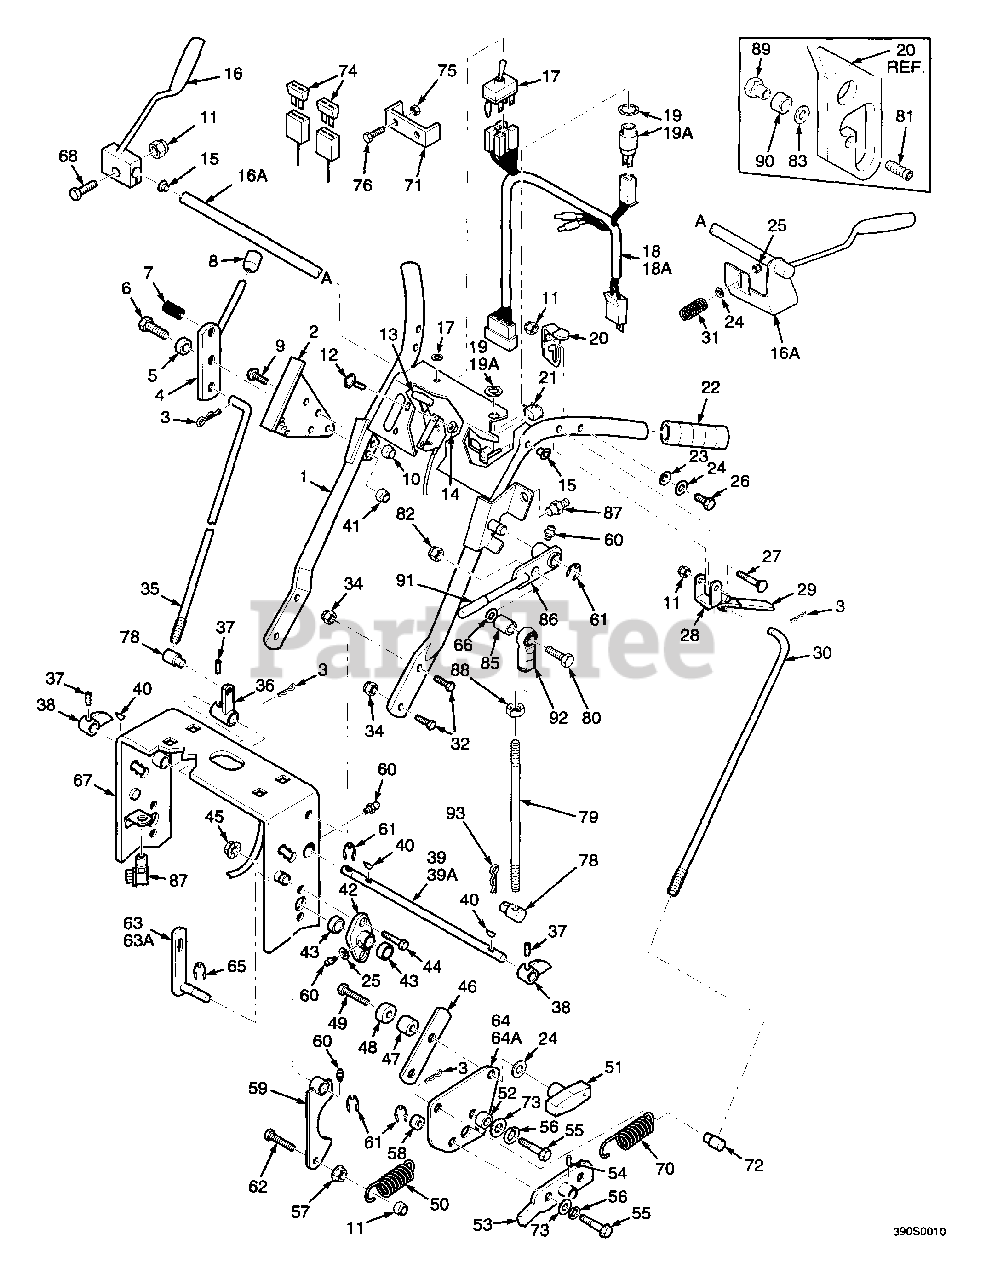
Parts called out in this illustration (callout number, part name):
1	Upper Handle Wlmt. W/Decals
2	Quadrant, Speed Control
3	Hairpin, .094 x 1.19
4	Lever, Speed Adjustment
5	Bushing, Speed Adjustment Lever
6	Hex Head Bolt, 3/8-16 x 1-1/2"
7	Ball Plunger
8	Knob, Speed Adjustment
9	Capscrew, 1/4-20 x 3/4" FHHS
10	Nut, 1/4-20 Elastic Stop
11	Nut, 5/16-18 Elastic Stop
12	Screw, #10-32 x 1/2" PW HD
13	Throttle Control
14	Nut, #10-32 Serr. Flange
15	Bushing
16	Handle, Operator Presence-RH
16A	Handle, Operator Presence-LH (20")
17	Switch, Elec. Clutch Eng.
18	Wire Harness, Manual Start
18A	Wire Harness, Electric Start
19	Key Switch, Manual Srt.
19A	Key Switch, Elec. Start
20	Neutral Latch-RH
20A	Neutral Latch-LH
21	Switch, Neutral Interlock
22	Grip
23	Washer, Curved Spring
24	Flat Washer
25	Lock Washer, 1/4" Int. Tooth
26	Hex Head Bolt, 5/16-18 x 2"
27	Hex Hd. Bolt, 5/16-18 x 2-1/2"
28	Lever, Steering Control
29	Grip, Steering Control
30	Rod, Steering Control
31	Spring, Handle Return
32	Capscr., 3/8-16 x 1" Ser. Flange
33	Lock Washer, 1/4"
34	Nut, 3/8-16 Serr. Flange
35	Rod Steering Control
36	Bellcrank, Speed Control
37	Setscrew, 1/4-28 x 1/4"
38	Cam, Speed Control
39	Jackshaft, Speed Control
40	Key, 1/8 x 1/2" Woodruff
41	Nut, 3/8-16 Elastic Stop
42	Pivot, Pump Ctrl
43	Bushing, 1/2" ID
44	Capscrew, 5/16-18 x 1" Serr. Flg.
45	Nut, 5/16-18 Serrated Flange
46	Bar, Speed Control
46	Bearing, Speed Ctrl. Bellcrank
47	Spacer, Speed Ctrl. Bearing
49	Hex Head Bolt, 5/16-18 x 1-3/4"
50	Spring, Return
51	Knob, Plastic
52	Bushing
53	Handle, Neutral Adj
54	Drive Pin, 5/32 x 7/8 Type U
55	HH Bolt, 5/16-18 x 3/4"
56	Lock Washer, 5/16
57	Nut, 5/16-18 Serr. Flange
58	Bearing, Ball Neutral Return
59	Cam, Neutral
60	Grease Fitting, 1/4-28 UNF
61	Retaining Ring, 5/8 Ext. "E"
62	Hex Head Bolt, 5/16-18 x 1"
63	Shaft, Pump Control-LH
63A	Shaft, Pump Control-RH
64	Bellcrank, Pump Control-LH
64A	Bellcrank, Pump Control-RH
65	Retaining Ring, 1/2 Ext. "E"
66	Flat Washer, 15/16 x 25/64 x 12 ga
67	Deck, Engine
68	Hex Head Bolt, 5/16-18 x 1-1/4"
69	Choke Control
70	Spring, Return
71	Fuse Holder
72	Swivel Joint, Steering Rod
73	Flat Washer (.344 x .688 x .065)
74	Blade Fuse, 20A
75	Nut, #10-32 Elastic Stop
76	Screw, #10-32 x 1-1/2" Phillips
77	Pin, Neutral Lock
78	Swivel Joint
79	Rod, Brake Lever
80	Hex Hd. Bolt, 3/8-16 x 1-3/4
81	Soc. Hd. Capscrew, #8-32 x 1/2
82	Nut, 3/8-16 Elastic Stop
83	Washer #8-.170 x .375 x .032
84	Retaining Ring, 5/8 Ext, "E"
85	Spacer
86	Parking Brake Lever with Grip
87	Switch, Parking Brake
88	Nut, 3/8-24
89	Bushing, Bearing Retainer
90	Bearing, Neutral Lock
91	Grip, Parking Brake
92	Ball Joint, RH Thread
93	Hairpin, .094 x 1.62
